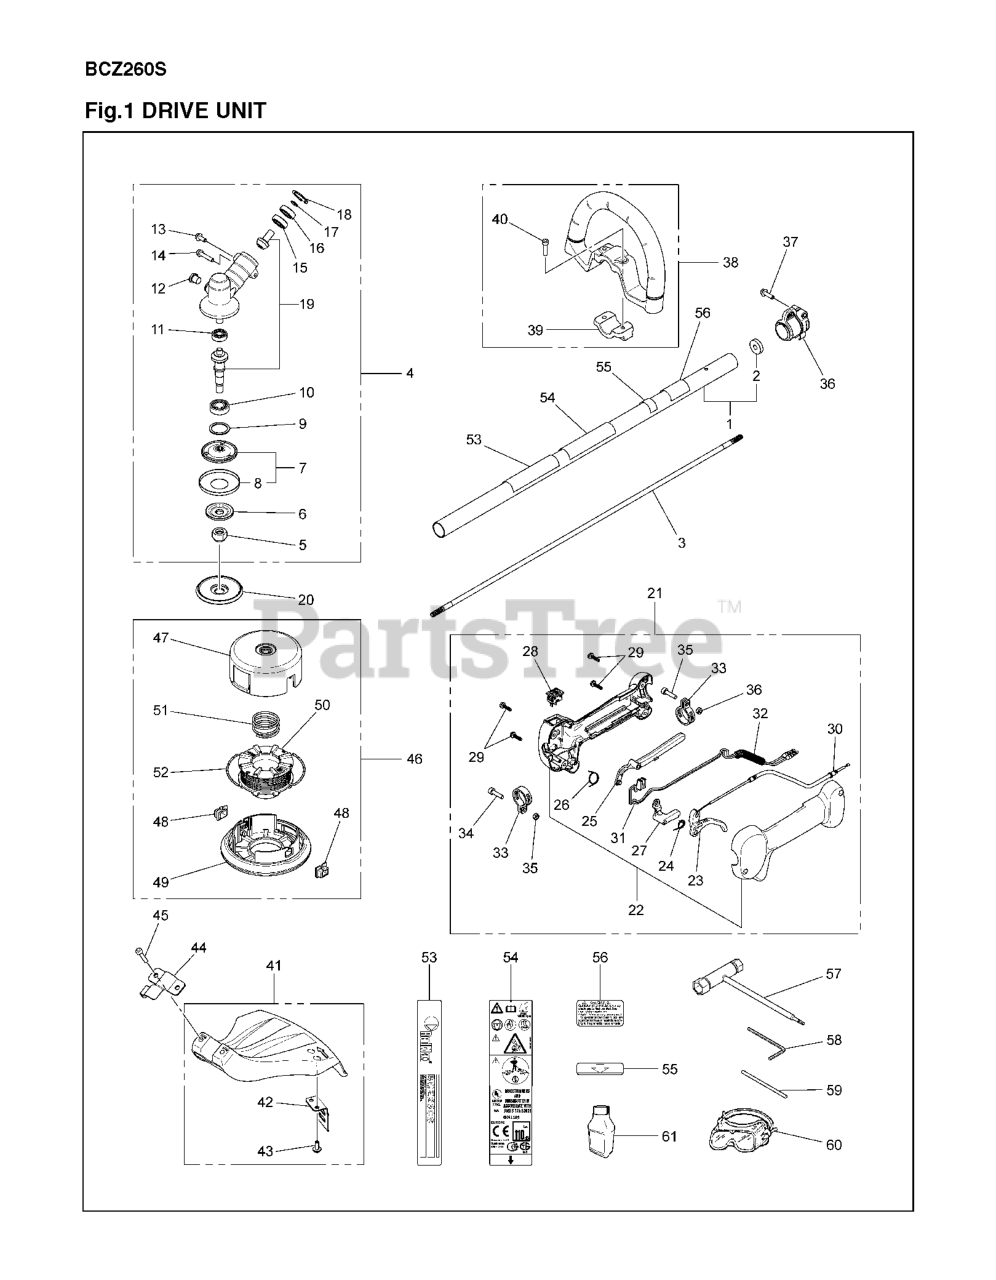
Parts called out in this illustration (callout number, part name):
1	TUBE
3	DRIVESHAFT 525L
4	GEAR HEAD
5	GEARHEAD NUT - BRUSHCUTTER
6	SUPPORT FLANGE
7	DRIVE DISC
8	WASHER
9	RETAINING RING SGH 28
11	BALL BEARING 8X22X7/608Z
12	PLUG
15	BALL BEARING 24X9X1/609ZR
17	RETAINING RING
18	RETAINING RING
19	GEAR SET
21	ASSY THROTTLE
22	GRIP HALF SET
23	LEVER, THROTTLE
24	SPRING, THROTTLE
25	LEVER, SAFETY
27	LEVER JOINT
28	STOP SWITCH NM_09091801
31	CORD - C
35	NUT
36	HANGER COMP.
38	HANDLE LOOP
39	CLAMP HANDLE
41	GUARD ASSY
44	BRACKET SHIELD
45	BOLT, TORX
46	TAP HEAD RPLS T318915100/02
47	CASE (RPL T318915112)
49	COVER (RPLS T318915131)
50	HOLDER, CORD (RPLS T318915141)
52	CORD
53	DECAL MODEL
54	DECAL WARNING
56	DECAL SPARK ARRESTOR WARNING
57	COMBINATION WRENCH TORX
58	L-SPANNER
59	LOCKING PIN
60	GOGGLExxx (RPLS
61	OIL 2 CYCLE ENGINE OIL 2.
